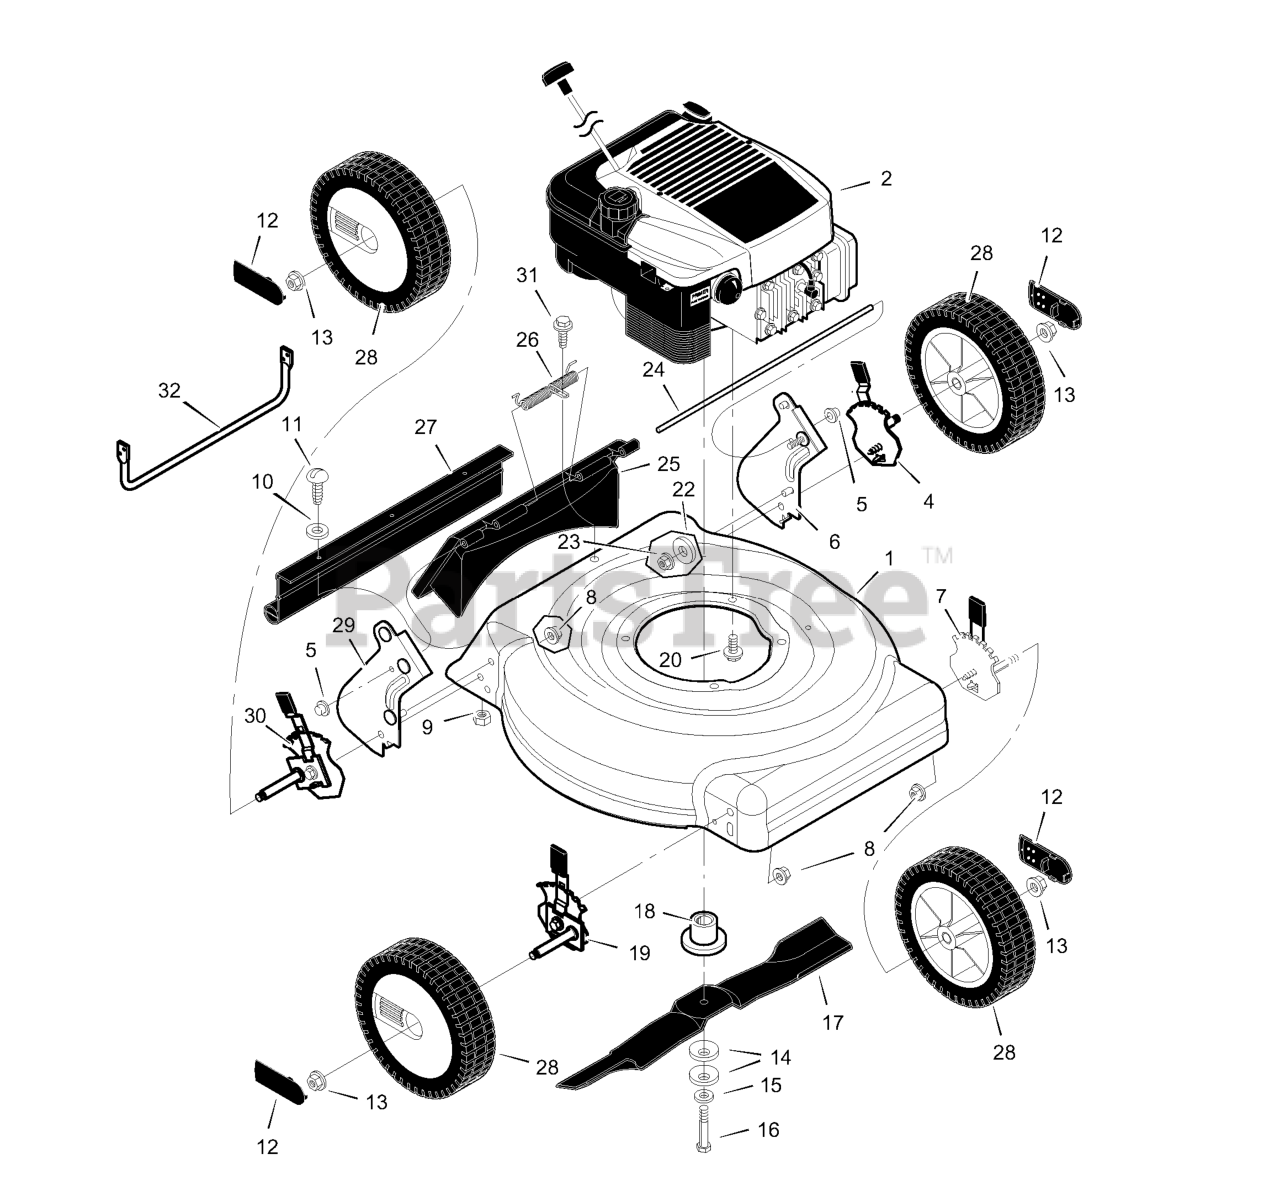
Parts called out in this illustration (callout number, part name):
1	Housing
2	Engine
4	Adjuster, Left Rear Height
5	Push On Cap
6	Bracket, Left Handle
7	Adjuster, Left Front Height
8	Nut, Flange
9	Nut, Hex
12	Hub Cap
13	Nut, Flange
14	Washer, Belleville
18	Adapter, Blade
19	Adjuster, Right Front Height
20	Bolt, Engine
22	Washer
23	Nut, Flange
24	Rod, Pivot
25	Door, Rear
27	Guard, Rear
29	Bracket, Right Handle
30	Adjuster, Right Rear Height
32	Guard, Rear
